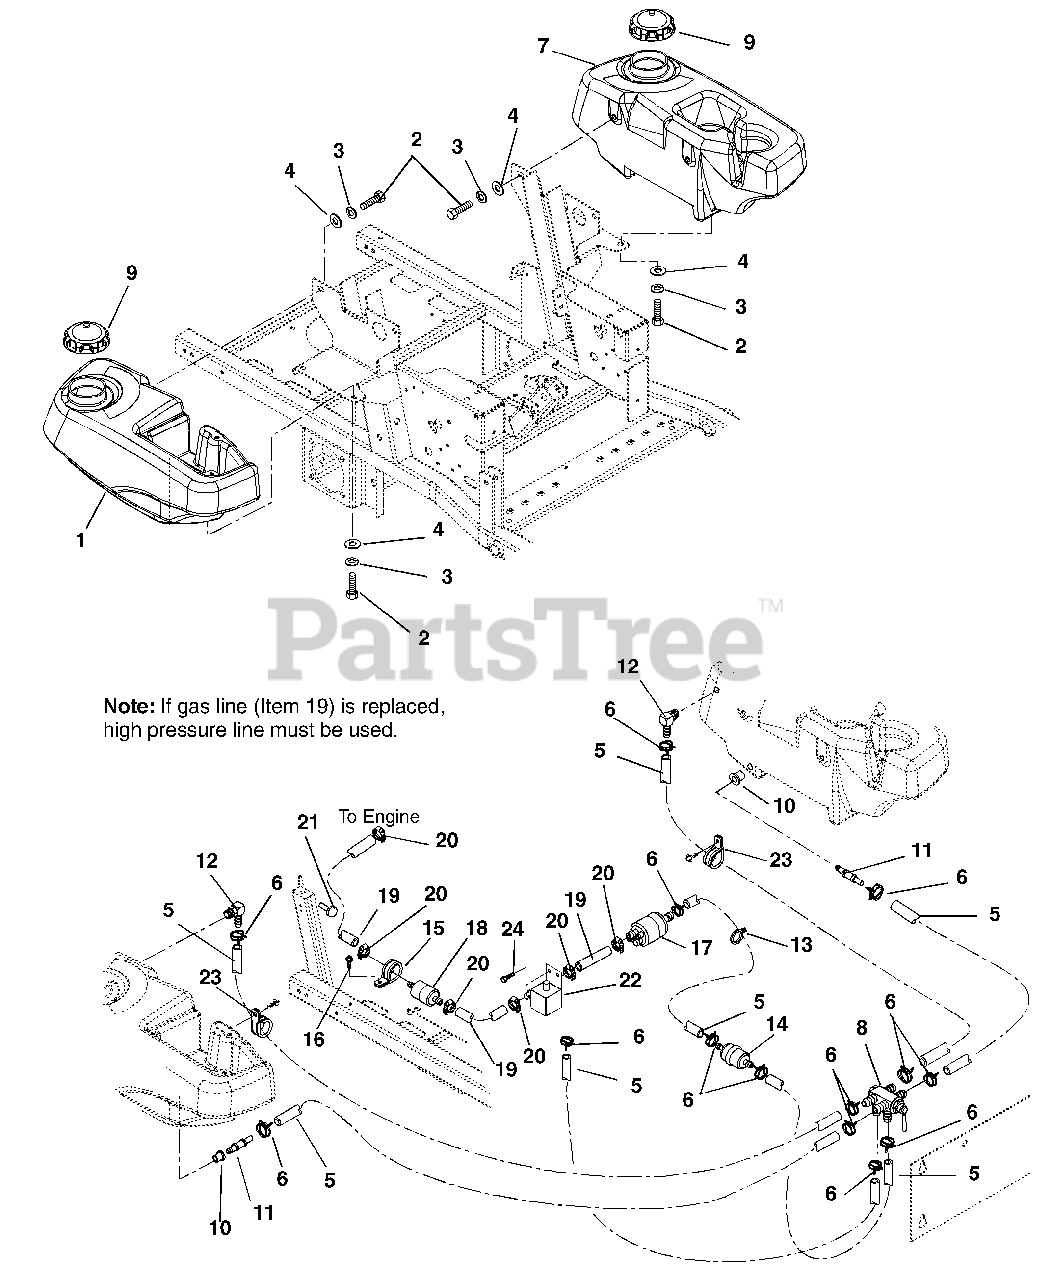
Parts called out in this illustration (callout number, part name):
1	Fuel Tank, Right Hand
2	Bolt-Hex .31-18 x .75 Grade 5
3	Washer-Locking .31 x .078
4	Washer-Flat-Steel .38 x .875 x .083
5	Hose, .31 ID
6	Hose-Clamp
7	Fuel Tank Left-Hand
8	Valve, Fuel
9	Cap-Gas
11	Fitting, Tank with Screen
12	Fitting, Tank
13	Tube Clip 1.50
14	Filter, Fuel .31
15	Clamp, 2.18
16	Screw-Tapping .38-16 x .75 Hex Washer Head
17	Pump, EFI Fuel
18	Filter, Fuel
19	Gas Line .31 ID High Pressure
20	Hose Clamp
21	Tube Clip .75
22	Regulator, EFI Fuel
23	Clamp, .50 I.D.
24	Screw-Tapping .25-20 x .37 Hex Washer Head
